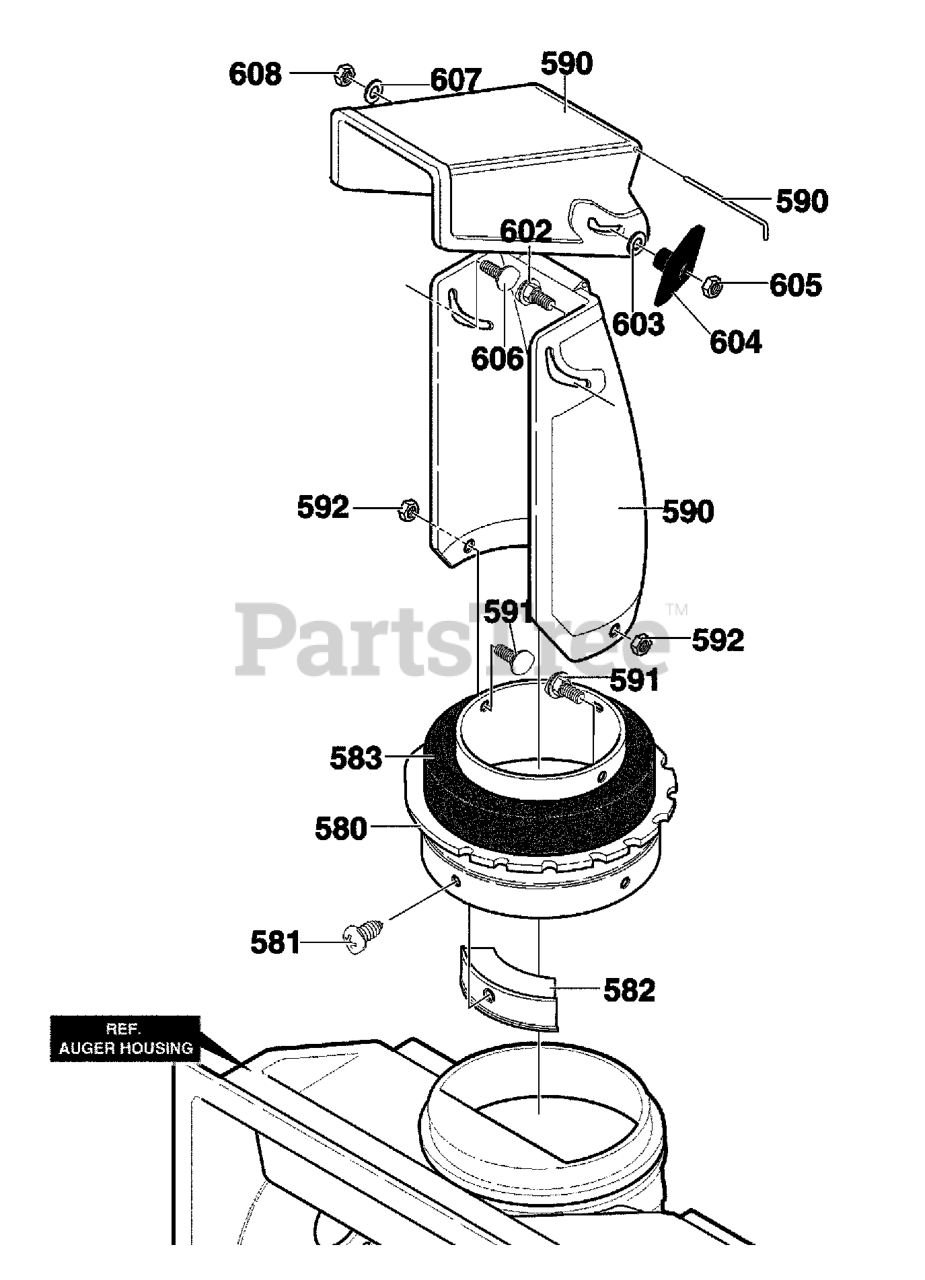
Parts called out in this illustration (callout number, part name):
580	RING, CHUTE
581	SCREW, #10X.50
582	GUIDE, CHUTE
583	DONUT FOAM
590	CHUTE ASSY.
591	SCREW 1/4-20X.50
592	NUT, CNTRLK 1/4-20
602	BOLT, 5/16-18X1.25 CARR.
603	WASHER, FLAT .349X.69X.066
604	KNOB, T
605	NUT, 5/16-18 REGHEX
606	SCREW, 5/16-18 x 0.75
607	WASHER, FLAT .349X.69X.066
608	NUT, 5/16-18 REGHEXCTRLK
